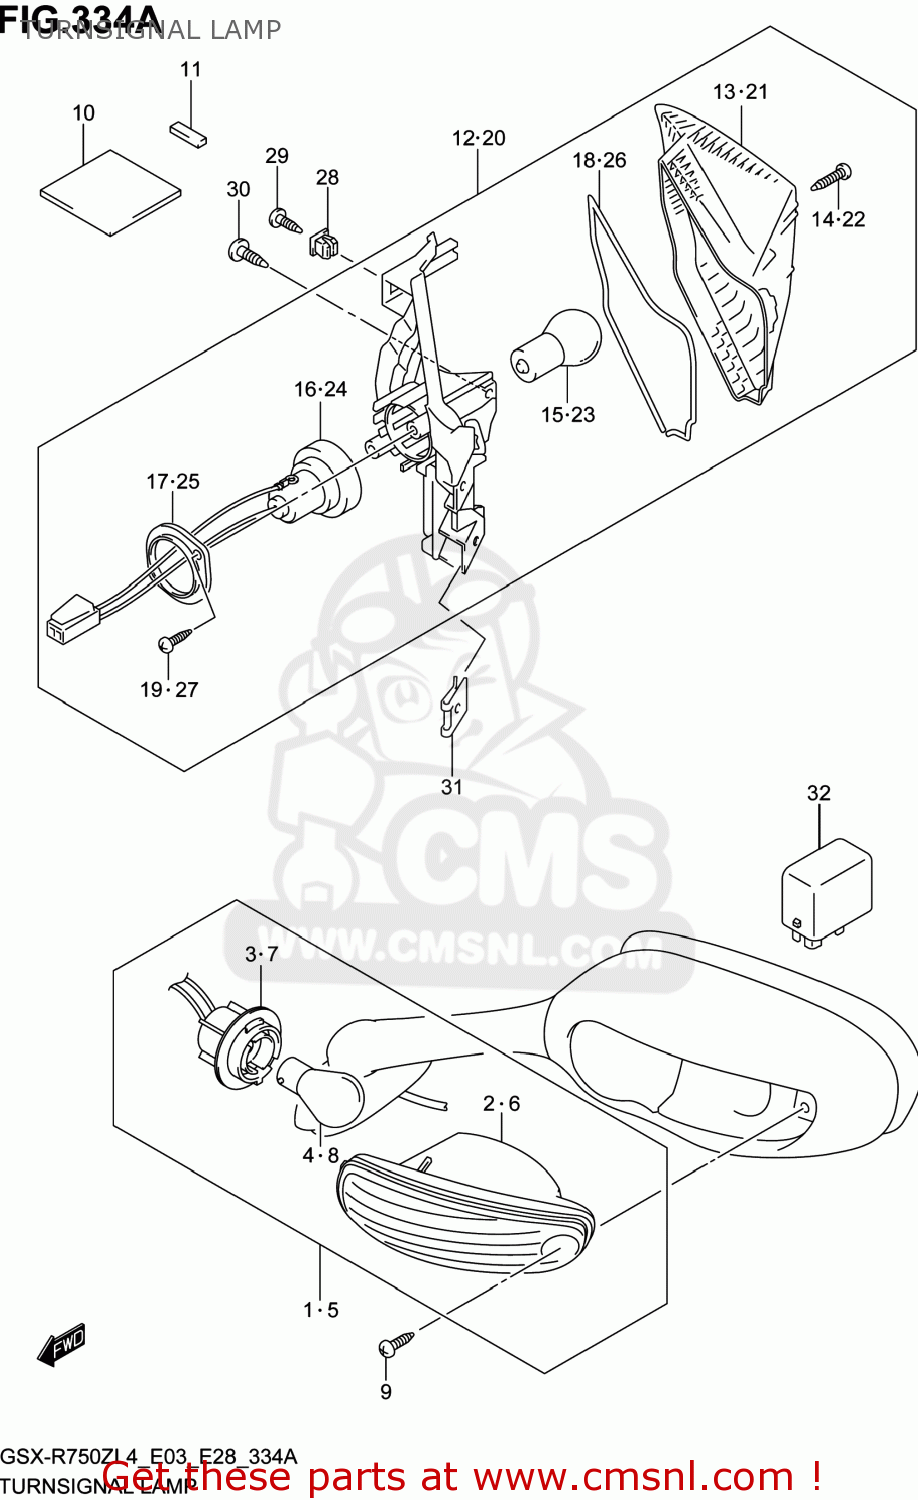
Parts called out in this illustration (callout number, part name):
1	LAMP ASSY,FR TURN SIGNAL,R
2	LAMP UNIT,R
3	SOCKET,R
4	BULB(12V21W,AMBER)
5	LAMP ASSY,FR TURN SIGNAL,L
6	LAMP UNIT,L
7	SOCKET,L
8	BULB(12V21W,AMBER)
9	SCREW(4X20)
10	CUSHION(40X20X5)
11	TAPE,FR TURNSIGNAL
12	LAMP ASSY,RR TURNSIGNAL,R
13	LENS,R
14	SCREW
15	BULB(12V21W,AMBER)
16	SOCKET & CORD,R
17	PLATE,RR COMBINATION
18	GASKET (NAS)
19	SCREW
20	LAMP ASSY,RR TURNSIGNAL,L
21	LENS,L
22	SCREW
23	BULB(12V21W,AMBER)
24	SOCKET & CORD,L
25	PLATE,RR COMBINATION
26	GASKET (NAS)
27	SCREW
28	NUT
29	SCREW
30	SCREW
31	NUT
32	RELAY ASSY,TURNSIGNAL LAMP
